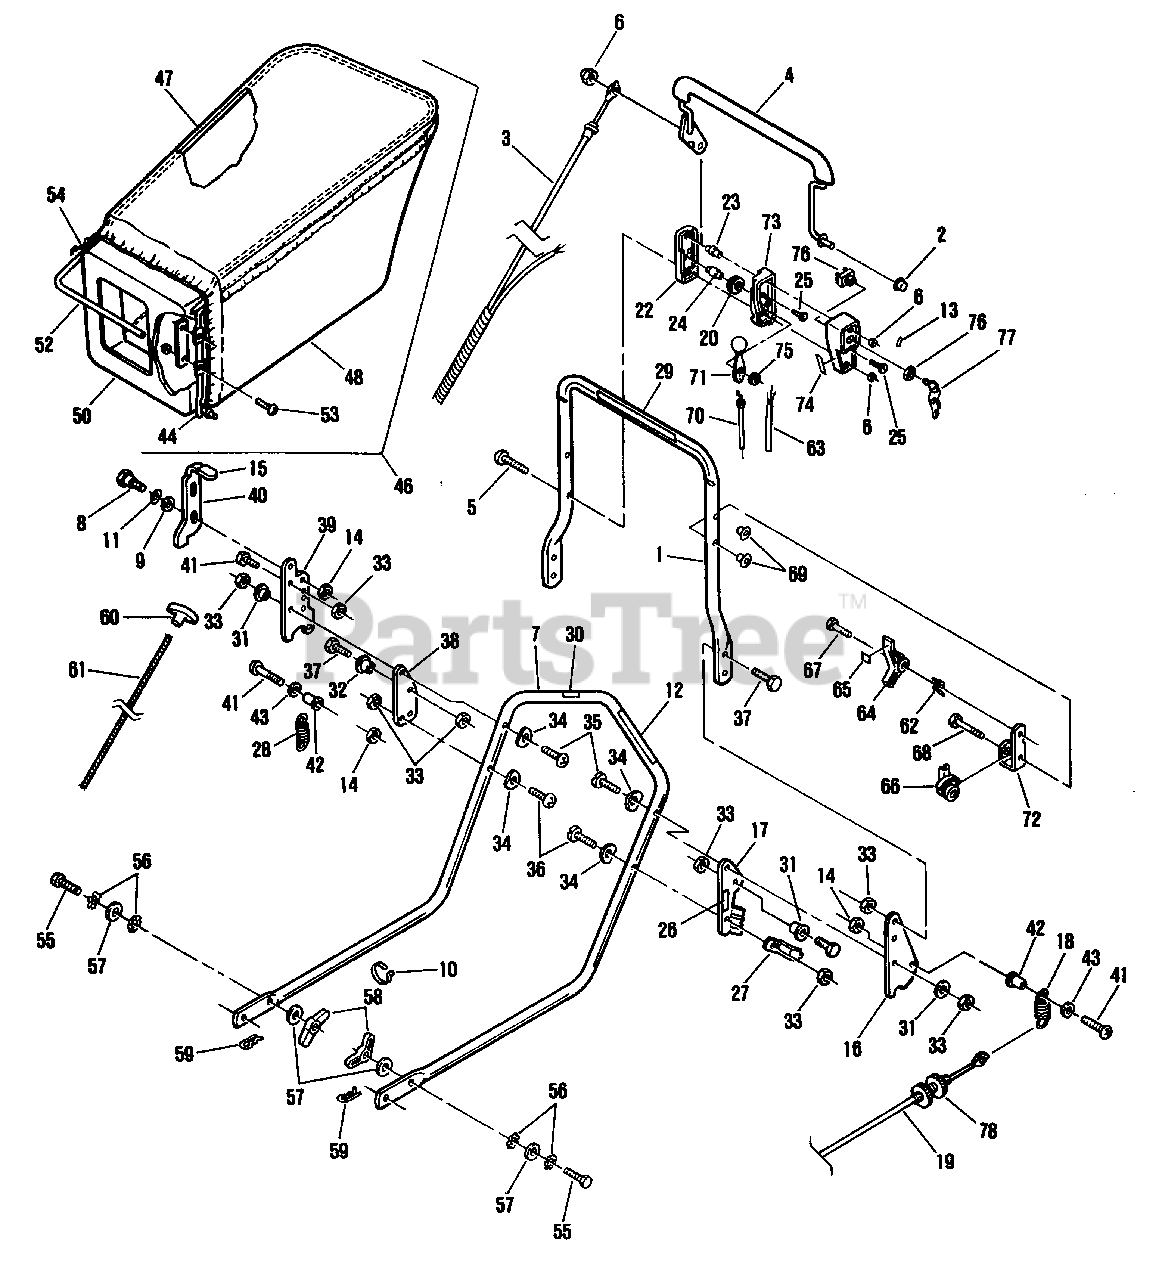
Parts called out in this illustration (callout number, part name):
1	Handle Section-Top
2	Pushnut
3	Control Cable Assembly
4	Control Lever Assembly
5	Truss Head Screw
6	Hex Locknut
7	Handle-Lower
8	Bolt-Shoulder
9	Washer
10	Tie Strap
11	Washer-Wave
12	Decal-Starting Instructions
13	Decal-On-Off
14	Locknut
15	Knob
16	Plate-Limit
17	Plate-Cable
18	Spring-Cable
19	Cable Assembly
20	Pulley
21	Control Case-Inner
22	Control Case-Outer
23	Column
24	Pin
25	Truss Head Screw
26	Decal-Drive Adjustment
27	Clamp-Cable
28	Spring-Return
29	Decal-Drive Control
30	Decal-Drive Lockout
31	Bushing
32	Bushing
33	Locknut
34	Washer-Curved
35	Truss Head Screw
36	Truss Head Screw
37	Screw
38	Pivot Plate
39	Limit Plate-Right
40	Slide Latch
41	Screw-Truss Head Machine
42	Spacer-Flanged
43	Washer
44	Eyebolt
45	Nut-Tube
46	Grass Catcher and Bag Assy.
47	Hanger-Bag
48	Grass Bag Assembly
49	Latch Bar Assembly
50	Bag Adapter
51	Nut-Bag Adapter
52	Bar-Reinforcing
53	Screw-Bar Adapter
54	Rope
55	Screw
56	Lockwasher
57	Washer
58	Wing Nut
59	Pin
60	Handle
61	Rope
62	Spring-Torsion
63	Wire Harness Assy.-Upper
64	Stop Latch Lever
65	Decal-Latch Lever
66	Cam Clutch Control
67	Bolt-Shoulder
68	Bolt-Shoulder
69	Nut-Tube
70	Cable-Throttle
71	Lever and Knob Assembly Throttle
72	Bracket-Bail Stop
73	Case Control-Center
74	Decal-Throttle Control
75	Washer-Spring
76	Switch Assembly
77	Keys (Two)
78	Thumb Nut
